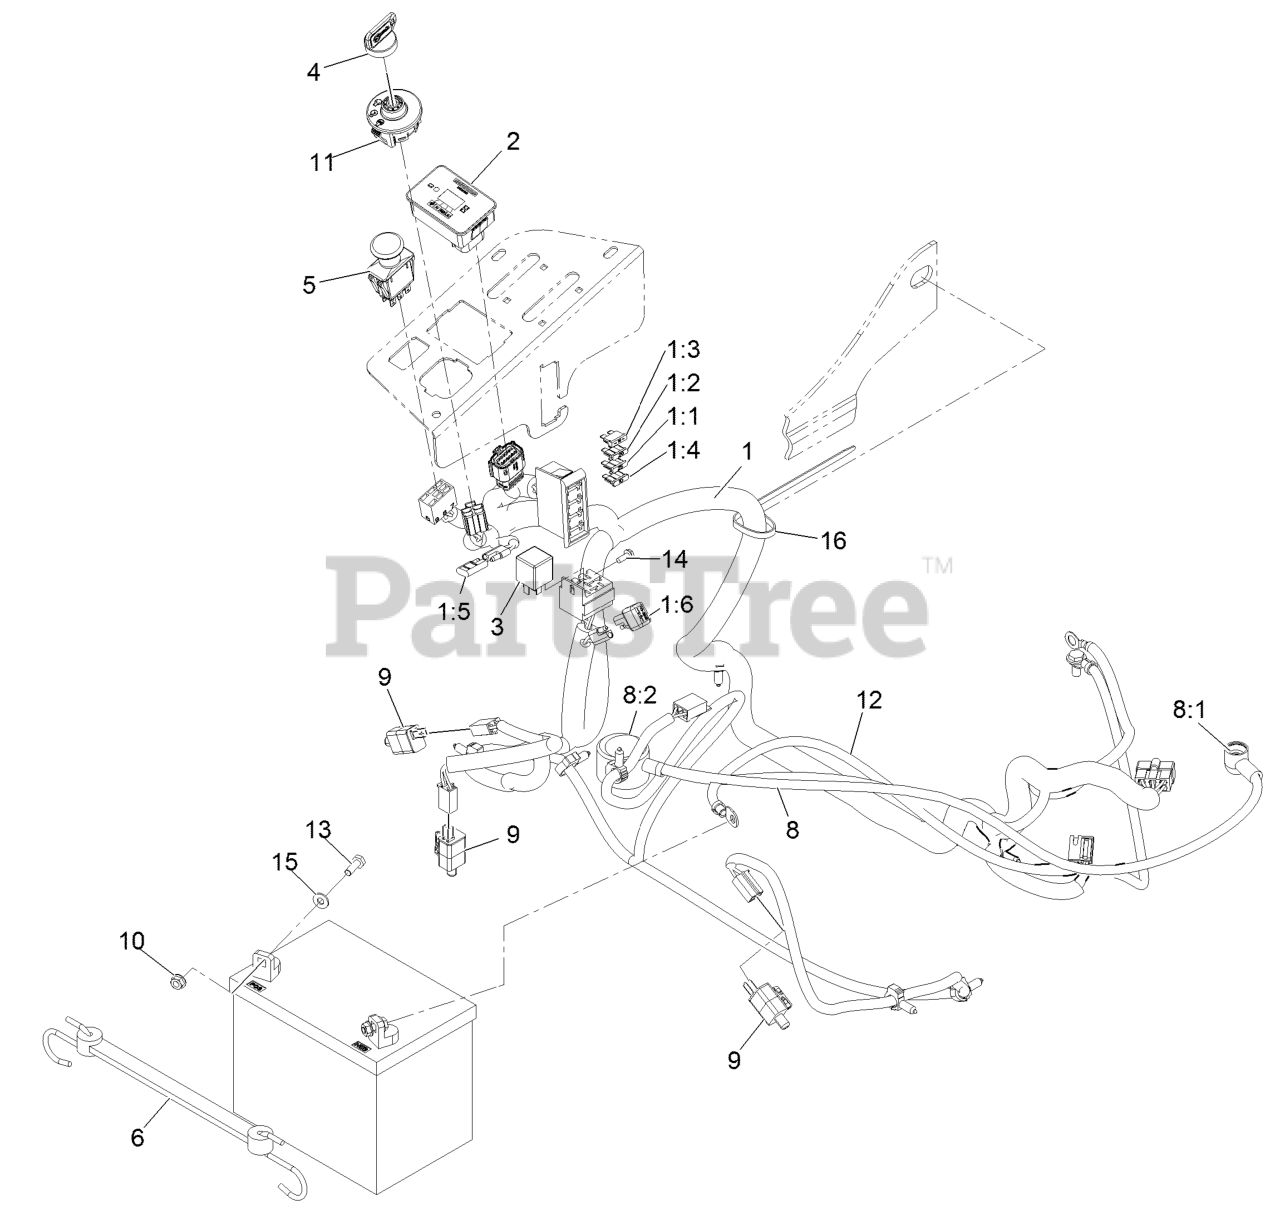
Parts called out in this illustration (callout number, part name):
1	HARNESS, WIRE
1:1	FUSE-BLADE, 25 AMP
1:2	FUSE-BLADE TYPE, 20 AMP
1:3	FUSE-BLADE, 15 AMP
1:4	FUSE-BLADE, 10 AMP
1:5	CAP-PLUG
2	MODULE ASM
4	KEY-IGNITION
5	SWITCH-PTO
6	HOLDDOWN-BATTERY
8	POSITIVE BATTERY CABLE AS
8:1	INSULATOR-SOLENOID
8:2	INSULATOR-BATTERY
12	CABLE-BATTERY, NEGATIVE
13	SCREW-HH
14	SCREW-TAPTITE
15	WASHER-FLAT
16	TIE-PLASTIC
